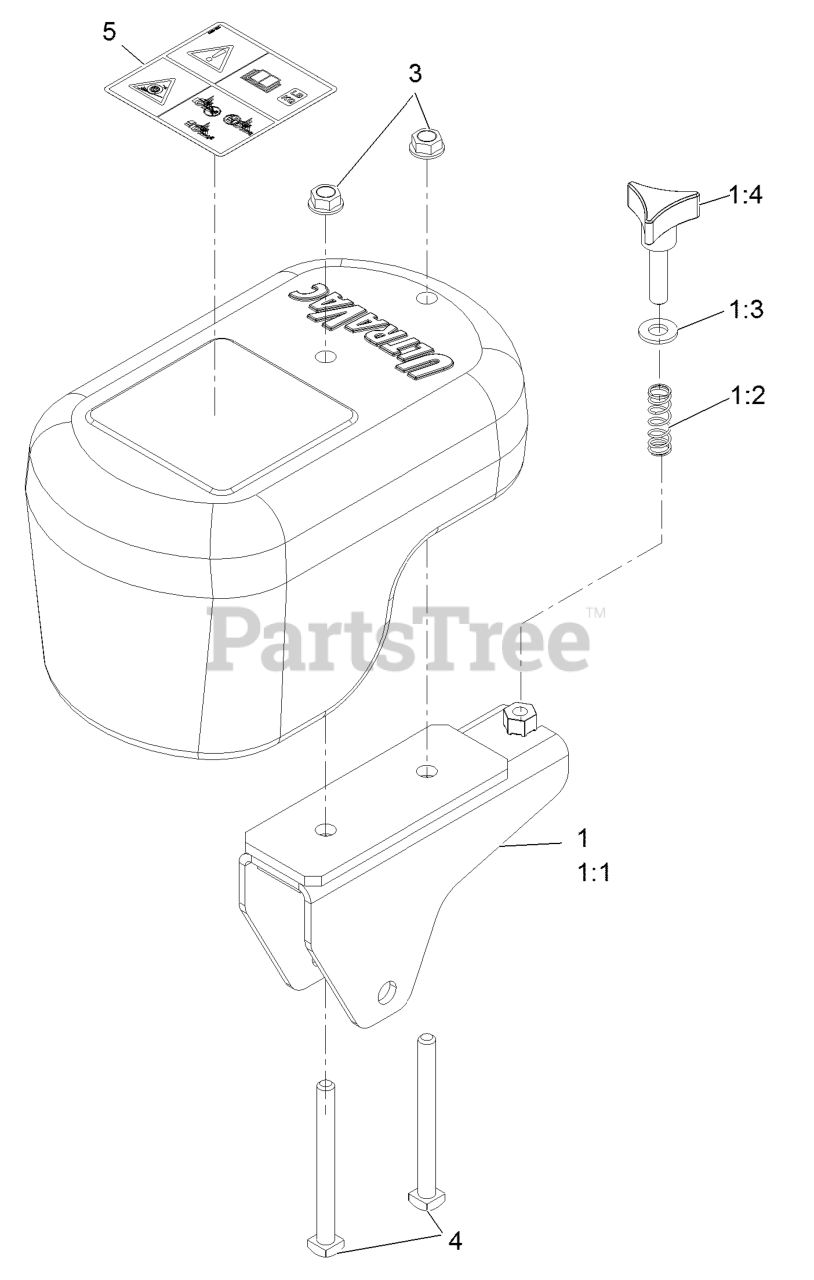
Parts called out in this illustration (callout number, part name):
1	ASM,CASTER WEIGHT BRACKET
1:1	WLD,CASTER WEIGHT BRACKET
1:3	WASHER-FLAT
3	NUT-HHF, WHIZ
4	BOLT, SQUARE HEAD YZ
5	DECAL-WARNING, TRACTION
